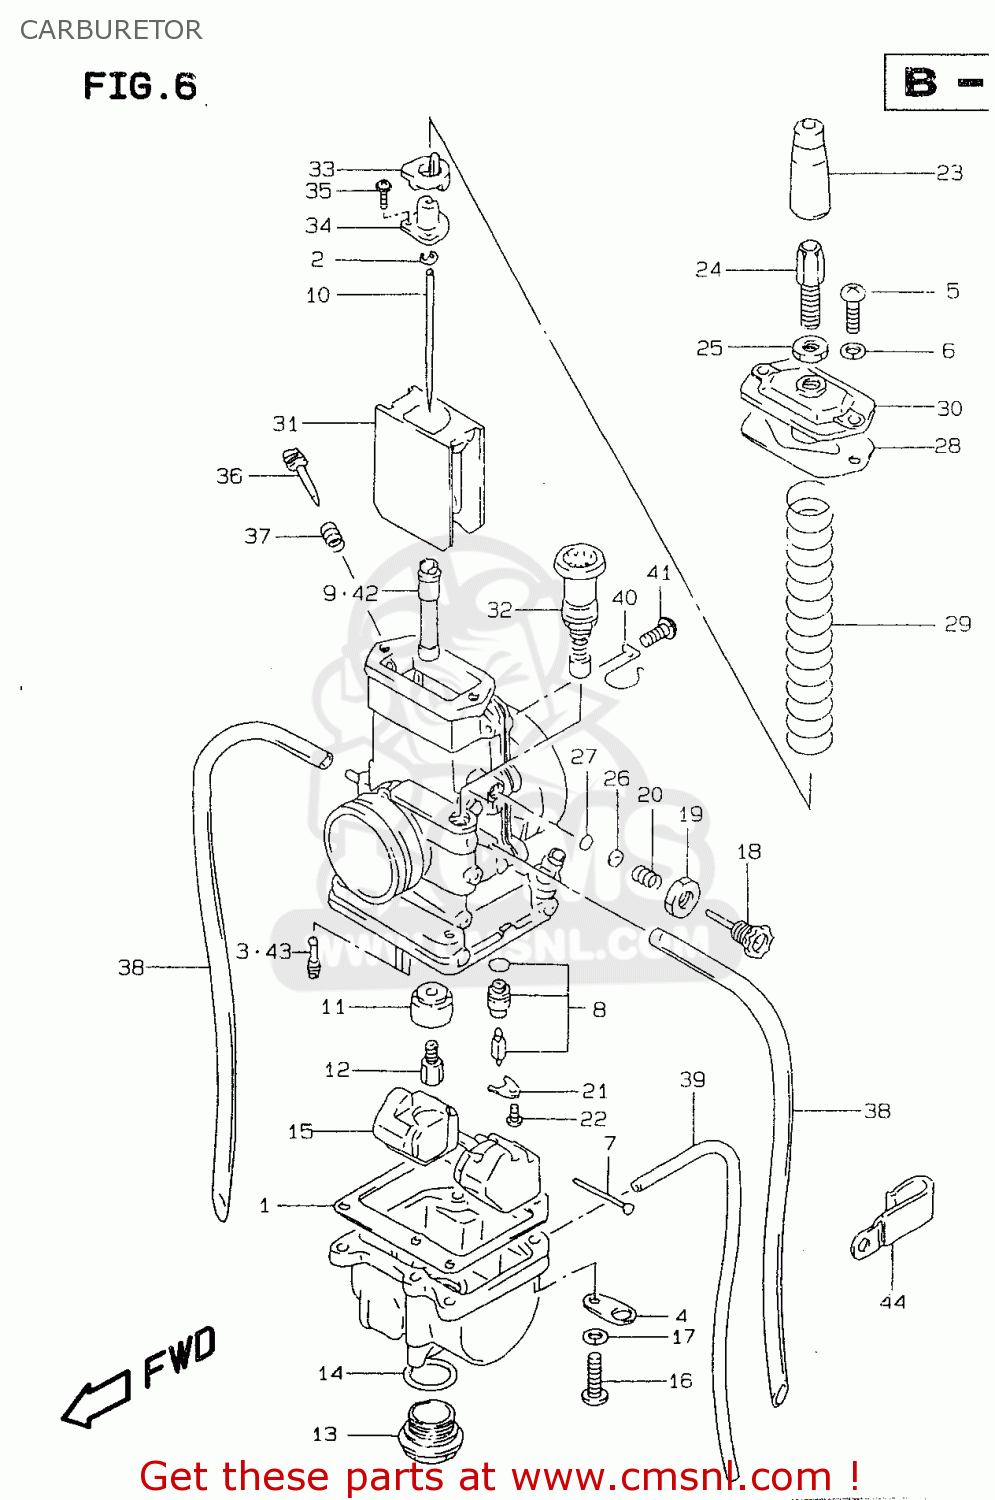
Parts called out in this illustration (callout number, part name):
1	GASKET,FLOAT CAHMBER (NAS)
2	CLIP
3	JET,PILOT(30)
4	PLATE,CARBURETOR
5	SCREW
6	WASHER,LOCK
7	PIN,FLOAT
8	VALVE ASSY,NEEDLE
9	JET,NEEDLE(P-4)
10	NEEDLE,JET(5DP39-4)
11	RING
12	JET,MAIN (210)
13	PLUG
14	O RING
15	FLOAT
16	SCREW
17	WASHER,LOCK
18	ADJUSTER,THROTTLE STOP
19	NUT
20	SPRING
21	PLATE
22	SCREW
23	CAP,CABLE ADJUSTER
24	ADJUSTER,CABLE
25	NUT
26	WASHER
27	O RING
28	GASKET,CARBURETOR TOP (NAS)
29	SPRING
30	CAP,CARBURETOR TOP
31	VALVE,THROTTLE
32	PLUNGER ASSY,STARTER
33	RING
34	JOINT
35	SCREW
36	SCREW,AIR
37	SPRING
38	HOSE(3.5X6.5X600)
39	HOSE(3X5X600)
40	CLIP
41	SCREW
42	JET,NEEDLE,P-2
43	JET,PILOT(25)
44	CLAMP
